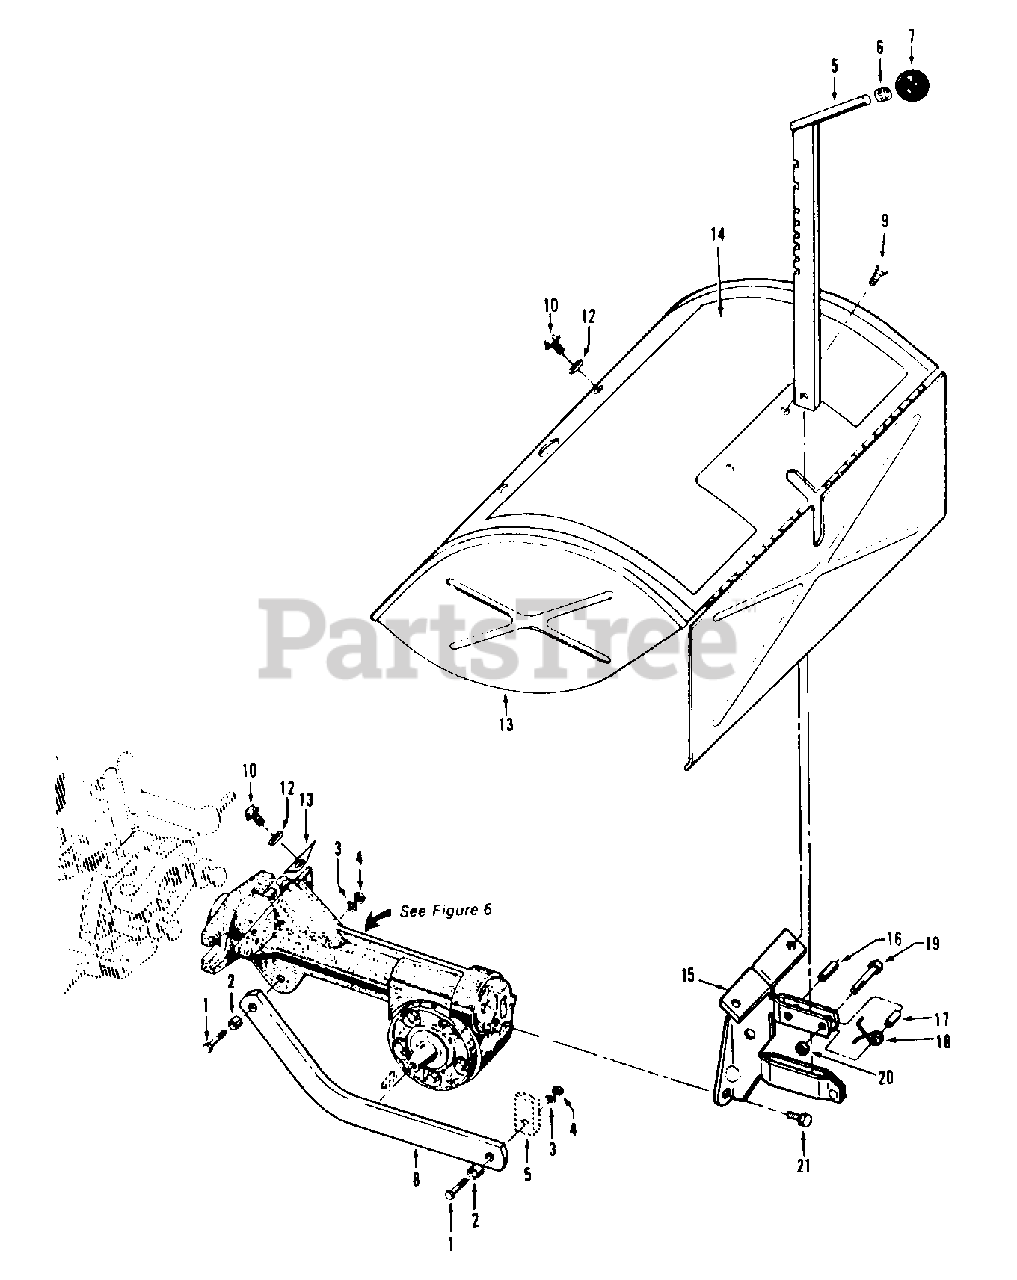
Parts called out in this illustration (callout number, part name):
1	Bolt-hex hd., 3/8-16 x 1-1/4"
2	Bushing - 19/64" (.300" lg.)
3	Lockwasher-spring lock, 3/8"
4	Nut-hex, 3/8"-16
5	Bar-depth regulator
6	Ring-retaining
7	Knob-depth regulator
8	Bar-drag, depth regulator
9	Screw-thread-forming, 1/4-20 x 1/2"
10	Bolt-flanged hex hd., 5/16-18 x 3/4"
12	Washer-flat, 5/16"
13	Hood
14	Decal-hood, operating instructions
15	Bracket
16	Pin-roll (spirol) 1/4" x 1"
17	Spacer
18	Spring
19	Bolt-hex hd., 1/4-20 x 1"
20	Locknut-1/4"-20
21	Bolt-flanged hex hd., 5/16-18 x 5/8"
